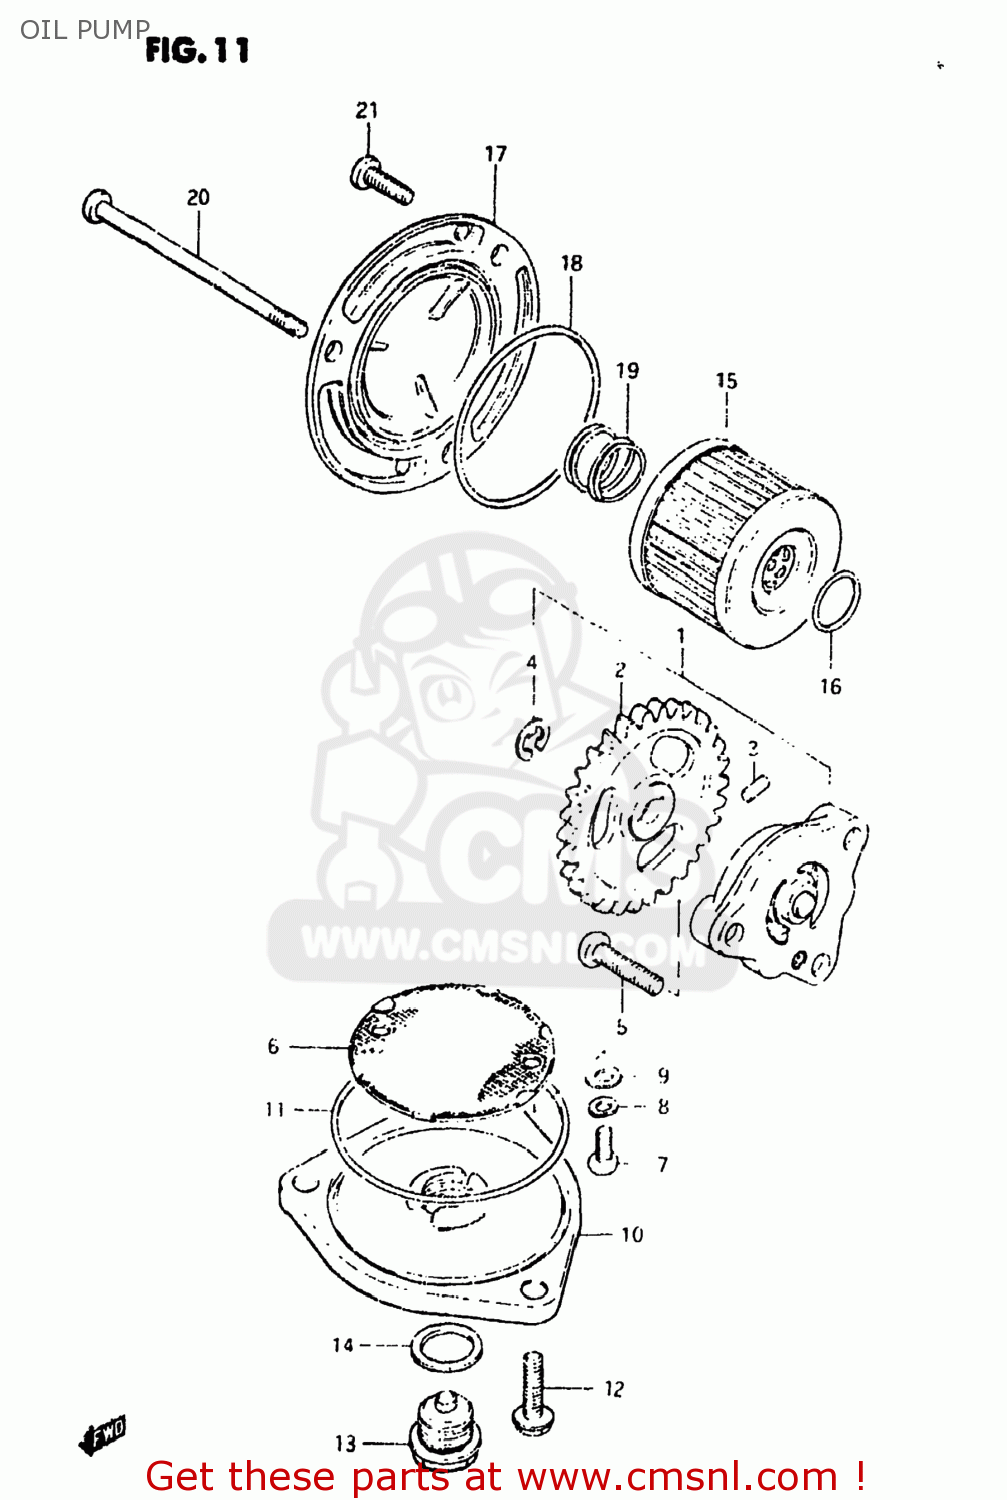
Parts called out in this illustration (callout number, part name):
1	PUMP ASSEMBLY,OIL
2	GEAR,ENG OIL PUMP DRIVEN(NT:30
3	PIN(2.5X11.8)
4	WASHER 6MM
5	SCREW
6	STRAINER,ENGINE OIL
7	SCREW
8	LOCK WASHER
9	WASHER
10	CAP,OIL STRAINER
11	O RING(D:2.4,ID:60.5)
12	BOLT,REAR
13	PLUG
14	GASKET(14X19.2X2) (NAS)
15	FILTER ASSY,ENGINE OIL
16	O RING(D:1.9,ID:13)
17	CAP,OIL FILTER
18	O RING(D:2.4,ID:52.6)
19	SPRING
20	SCREW
21	SCREW
